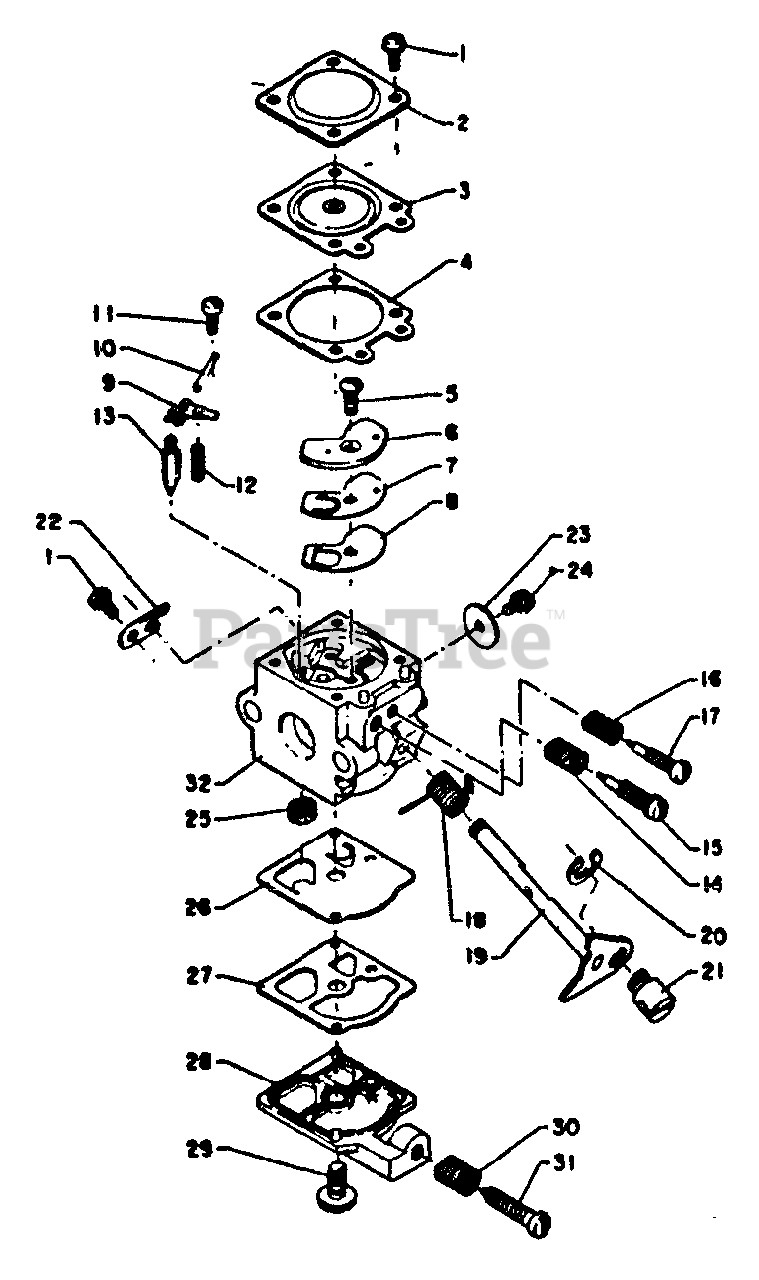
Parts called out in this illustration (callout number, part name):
2	COVER, METERING DIAPHRAGM
3	DIAPHRAGM, METERING
4	GASKET, METERING DIAPHRAGM
5	SCREW, CIRCUIT PLATE
6	PLATE, CIRCUIT
7	VALVE, CHECK
8	GASKET, CIRCUIT PLATE
9	LEVER, METERING
10	PIN, METERING LEVER
11	SCREW, METERING LEVER PIN
13	VALVE, INLET NEEDLE
14	SPRING, NEEDLE
15	NEEDLE, HIGH SPEED
16	SPRING, NEEDLE
17	NEEDLE, IDLE
18	SPRING, THROTTLE RETURN
19	SHAFT, THROTTLE
20	RING, RETAINING
22	CLIP, THROTTLE SHAFT
23	VALVE, THROTTLE
25	STRAINER
26	DIAPHRAGM, FUEL PUMP
27	GASKET, FUEL PUMP
28	COVER, PUMP
30	SPRING, IDLE ADJUST
31	SCREW, IDLE ADJUST
32	BODY, CARBURETOR
